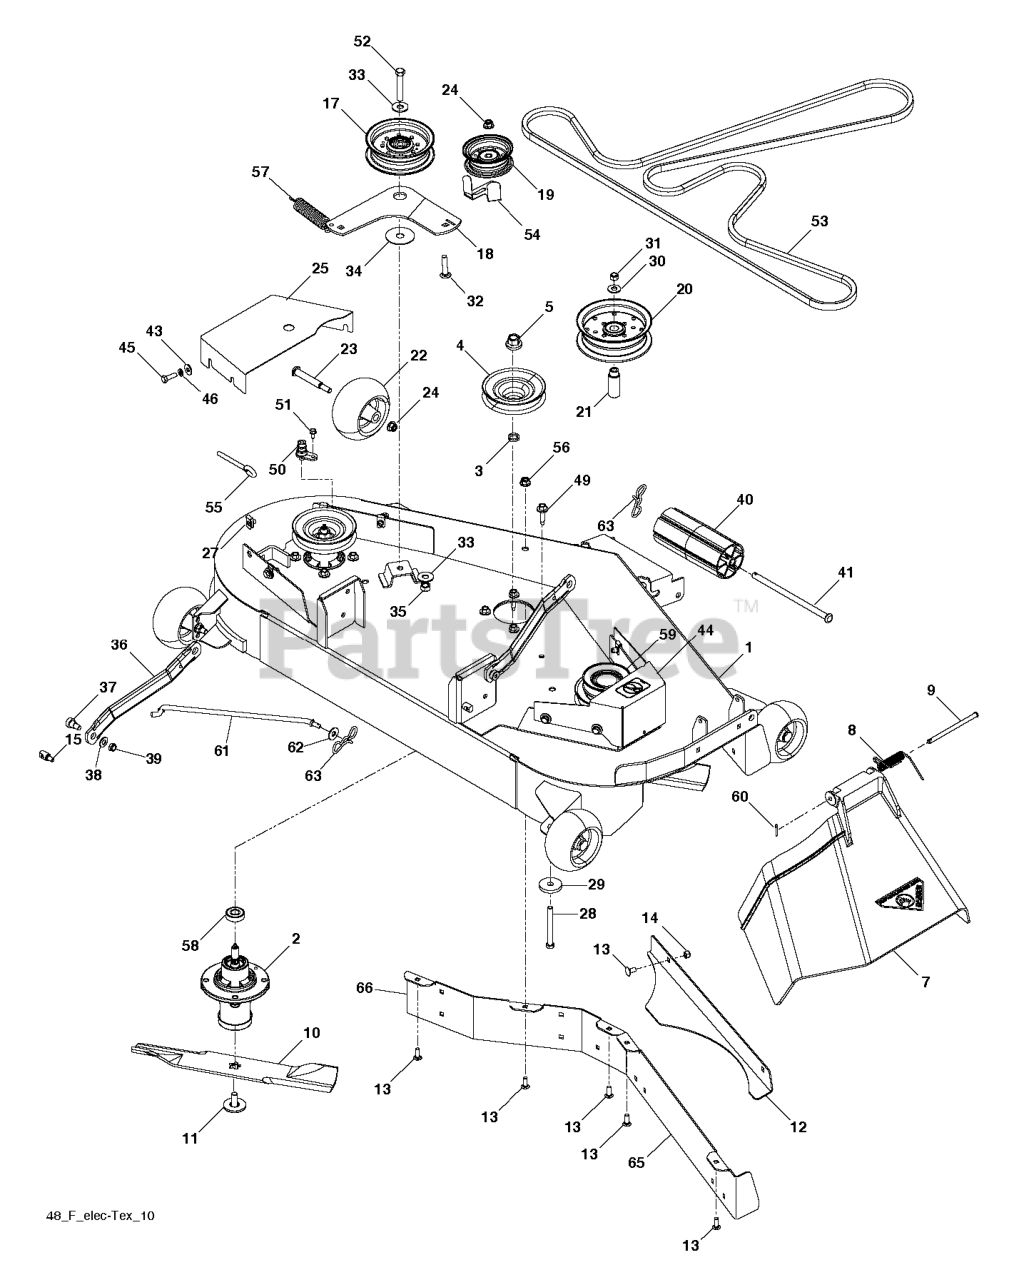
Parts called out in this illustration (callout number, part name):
1	DECK.WLD.PNT.48BLT-ON.BFFL.498
2	MANDREL.DECK.ASSEMBLY
3	WASHER.SPACER.MANDREL
4	PULLEY.DRIVEN.DECK.48'
5	NUT.FLANGE.LOCK.TOP
7	DISCHARGE CHUTE 48"
8	SPRING - TORSION
9	PIN-CLEVIS 5/16 DIA X 5.19 ZD
10	BLADE, 16-1/4"
11	BOLT.WASHER.ASM.7/16-2
12	PLATE.CONFINEMENT.48"
13	BOLT.CARR.5/16-18X5/8.SHORT
14	NUT.71038.31-18.HEX.NYLOCK
15	STUD.FASTNER.W/ANTI-ROTATE
17	PULLEY.IDLER.MWR.STATI.LH
18	ARM IDLER RAW
19	PULLEY.IDLER.FLAT
20	PULLEY, IDLER
21	BUSHING, IDLER
22	WHEEL GAGE DONUT
23	BOLT.SHOULDER.3/8-16X3-5/8.
24	NUT 3/8-16 HEX FLG NYLOC ZD
25	SHIELD.BELT.LH.52.PNT.498
27	U-CLIP 5/16-18 NUT RETAINER
28	HCS 3/8-16 X 3-1/2 GR5 ZD
29	SPINDLE WASHER
30	RP WASHER 3/8 FLAT
31	NUT 3/8-16 NYLOC
32	RHSNB 3/8-16X1-3/4
33	WASHER 7/16 FLAT ZD
35	NUT 7/16-14 HEX WHIZ LK SMOOTH
36	ARM.SUSPENSION.MOWER
37	SB 3/8-16 X 3/8 SKT HD ZD
38	WASHER
39	NUT HEX 3/8-16 NYLON, THIN
40	NOSE ROLLER 48"
41	ROD.ROLLER.NOSE.NARROW.48"
43	WASHER.5/16.FLAT.STE.STD.
44	SHIELD.BELT.RH.48.X498
45	BOLT.FIN.HEX.5/16-18UNC X 1.00
46	WASH.5/16.SLW.ZD
49	BOLT.HEX.WASHR.HED.313-18X1.19
50	PORT.WASHOUT
51	SCREW
52	BOLT.HEX.7/16-14
53	BELT, 135" EL
54	GUARD, BELT
55	EYE BOLT 5/16 X 3.50
59	RP PULLEY, COLLECTION 48
60	RETAINER CLIP
61	ROD.ANTI.SWAY.48/54"K4
62	WASHER
63	PIN.COTTER.5/16.BOW TI
